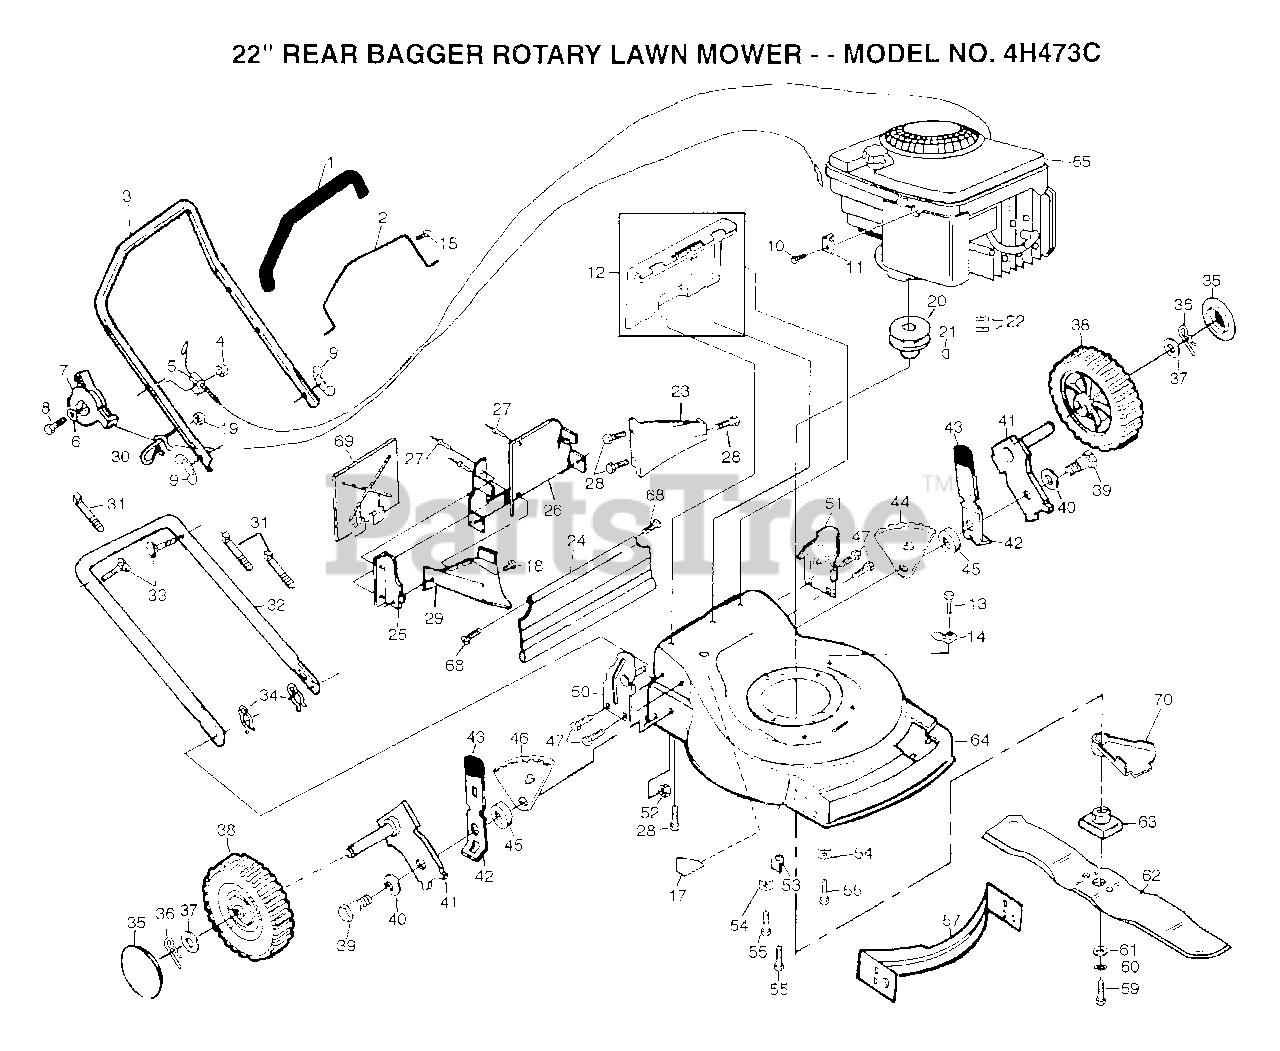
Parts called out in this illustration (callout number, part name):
2	"BAR,CONT"
5	"CABLE,ENG ZONE CO"
6	WASHER PM
7	"CONTROL, THROTTLE"
9	"NUT,WING PM"
10	SCREW PM
11	CABLE CLAMP
13	TAPPING SCREW
14	GUIDE CLIP PM
15	"SCREW,PAN HD"
17	DECAL HYT
18	SCREW PM
19	NUT
20	ENGINE.PULLEY.FWG
21	HI PRO KEY PM
22	SCREW
23	REAR BAFFLE
26	PLATE.BACK
27	BLIND RIVET
28	SCREW
29	DISCHARGE BAFFLE
30	ROPE GUIDE
33	BOLT.HANDLE.LM
34	HAIRPIN COTTER
35	HUB CAP
36	RETAINER CLIP PM
37	WASHER
40	"WASHER, BELLEVIL."
41	AXLE ARM
42	SPRING SELECTOR
43	KNOB PM
44	BRACKET.ADJ.9.LH
46	BRACKET.ADJ.9.RH
47	SCREW
52	LOCKNUT PM
53	DEBRIS SHLD RET
55	SCREW
59	SCREW
60	LOCKWASHER
61	"WASHER,HARDEN"
63	ADAPTOR.BLADE.LM
64	KIT.HSG.22RD.FWGD
68	HINGE SCREW
69	MULCHER PLATE
